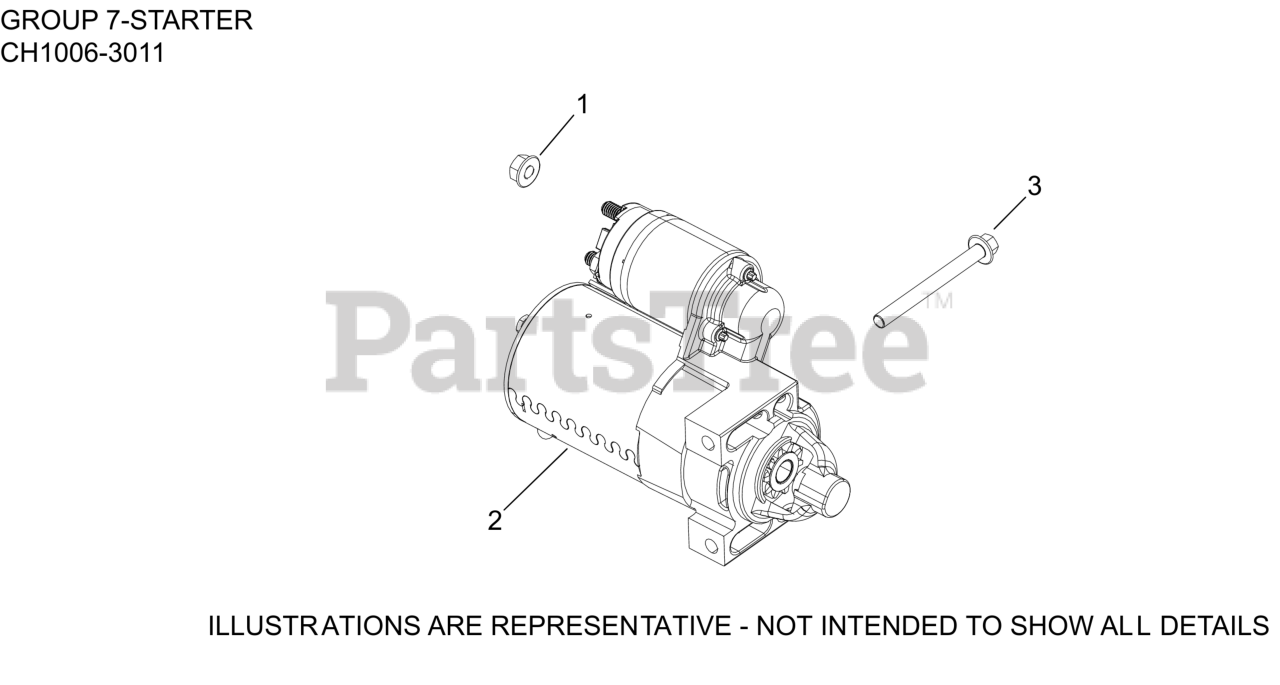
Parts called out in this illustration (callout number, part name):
1	NUT, FLG M8X1.25
2	STARTER, SOLENOID SHIFT
3	SCREW, FLG M8X1.25X80
